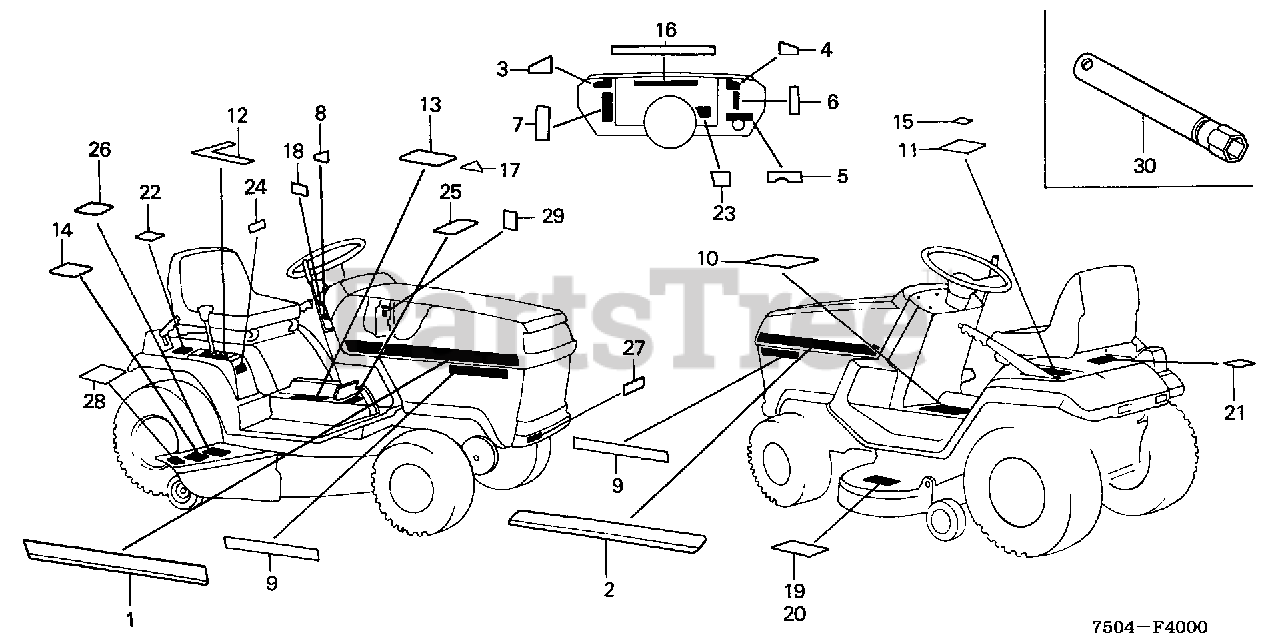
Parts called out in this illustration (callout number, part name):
1	MARK, R. SIDE STRIPE
2	MARK, L. SIDE STRIPE
3	MARK, THROTTLE
4	MARK, LIGHT SWITCH
5	MARK, ENGINE SWITCH
6	MARK B, LIGHT SWITCH
7	MARK, THROTTLE (ENGLISH)
8	MARK, P.T.O.
10	LABEL, WARNING (E) (NOT AVAILABLE)
11	MARK, ADJUSTING LEVER (NOT AVAILABLE)
12	MARK, SHIFT GUIDE (NOT AVAILABLE)
13	LABEL A, OPERATION (NOT AVAILABLE)
14	LABEL B, WARNING (ENGLISH)
15	MARK, INDICATOR
16	MARK, PARKING BRAKE INDICATOR
17	LABEL, BRAKE
18	MARK, P.T.O. CLUTCH
20	LABEL A, WARNING (ENGLISH)
21	LABEL, FUEL WARNING (A)
21	LABEL, FUEL WARNING (B)
22	LABEL B, PARKING BRAKE
25	LABEL, PARKING BRAKE
26	MARK, INCH SIZE (38)
27	LABEL, BELT CAUTION (E)
29	MARK, OIL CAUTION
